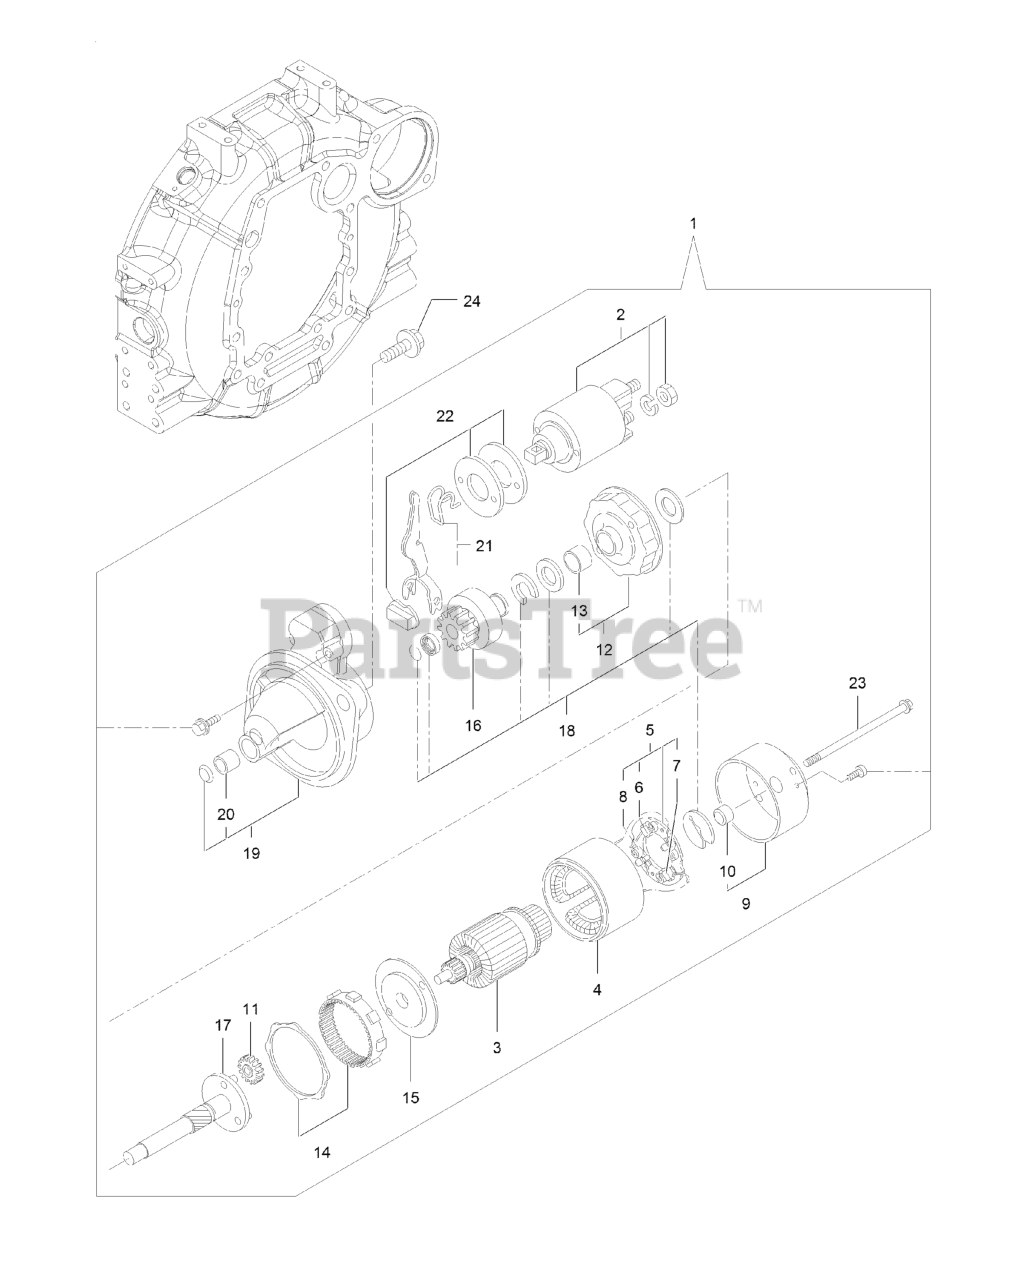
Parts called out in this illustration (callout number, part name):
1	STARTER ASM
2	SWITCH ASM
3	Armature ASM
4	Yoke ASM
5	Brush Holder ASM
7	BRUSH SET
9	Cover ASM
12	Bracket
13	Bracket
15	Bracket
16	PINION ASM
18	Washer Set
19	Case ASM
20	Metal-Starter
21	Lever Set
22	Dust Cover ASM
23	BOLT-THROUGH
